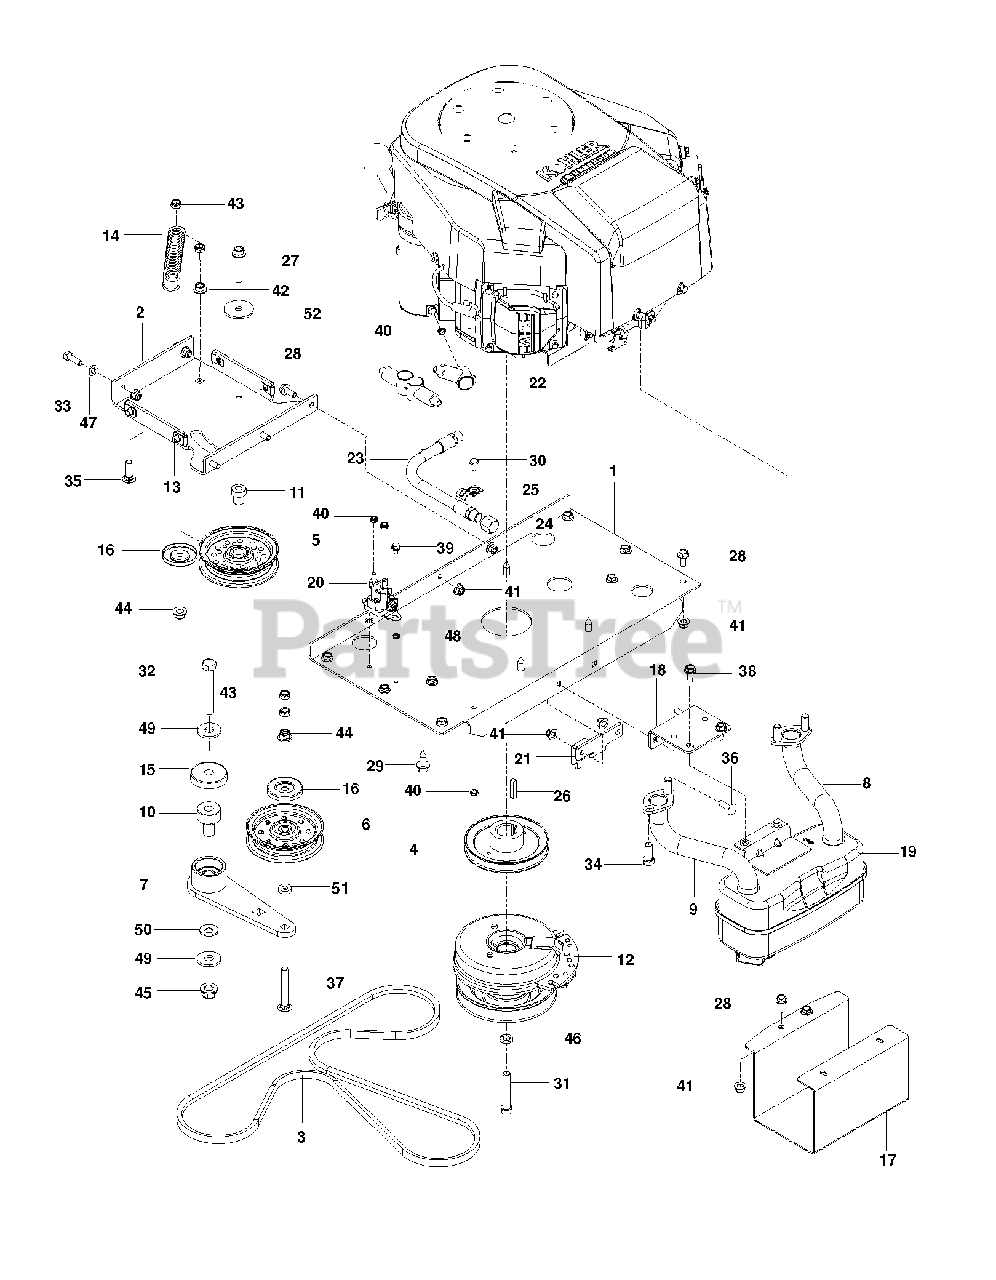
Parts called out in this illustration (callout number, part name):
2	PLATE, IDLER, BLK
3	BELT, HYDRO, 3400
4	PULLEY, V, 1.125 BORE
5	IDLER PULLEY
7	ARM, IDLER, STEEL, W/BGS
8	PIPE-EXHAUST LH
9	PIPE-EXHAUST RH
10	PIVOT, BEARING
11	PIVOT, IDLER
12	CLUTCH 200 FT LB
13	U-CLIP 5/16-18 NUT RETAINER
14	SPRING, PUMP
15	SHIELD, DUST
16	DUST SHIELD
19	MUFFLER ASM TWIN
20	SOLENOID
22	INSULATOR
23	OIL DRAIN HOSE
24	DRAIN CAP
26	KEY, 1/4 SQ X 1 1/4
27	HHFS 3/8-16 X 2.0 GD 5
28	HHFS 5/16-18 X 3/4
29	HHFS 3/8-16 X 1.0 THD FORMING
30	HCS 1/4-20.
31	BOLT 7/16F X 2 1/2
32	HCS 1/2C X 3 1/4
33	HCS 5/16C X 1
34	HCS 5/16C X 3/4
35	RHSNB 3/8-16 X 1-1/4
36	RHSSNB 5/16C X 1.0
37	RHSNB 3/8-16 X 2.75
38	BOLT 5/16-18 X 3/4
39	HWST 1/4C X 3/8
40	JAM NUT 1/4C
41	5/16-18 NYLOC FLANGE NUT
42	NUT 3/8C WHIZ
43	NUT HEX 3/8-16 NYLON, THIN
44	NUT 3/8-16 HEX FLG NYLOC ZD
45	NUT, 1/2-13 HEX FLG NYLOC ZD
46	WASHER 7/16 LOCK
47	FLAT WASHER 5/16 SAE
48	WASHER 1/4 INT TOOTH
49	WASH USS FLAT 1/2
50	CONTACT BELLSPR 1/2
51	WASHER 3/8 X 3/4 X .187 TK
52	WASHER, 3/8 SPEC
